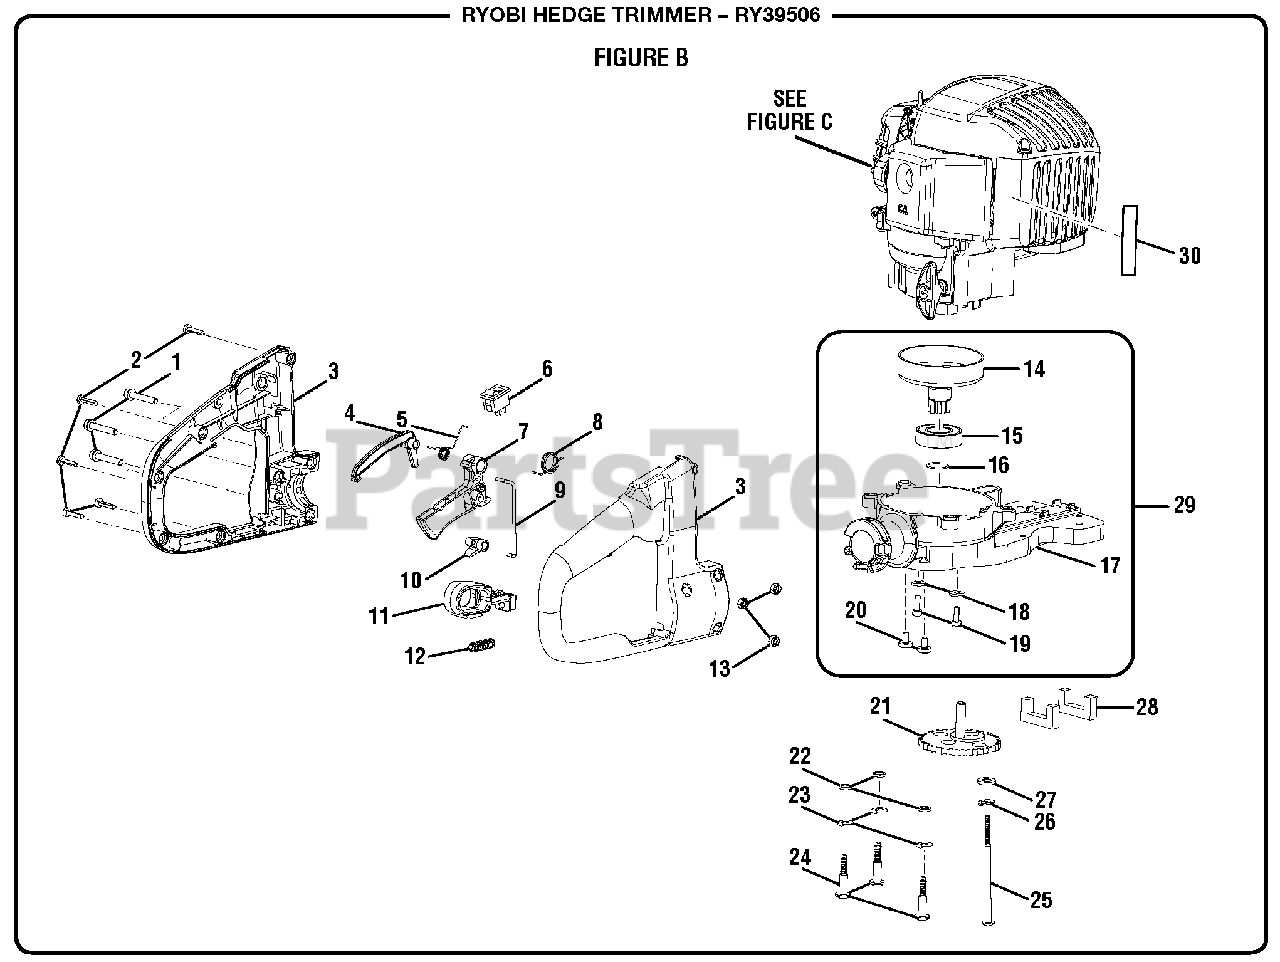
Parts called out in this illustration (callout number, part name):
1	Screw (M5 x 28 mm)
2	Screw (M4 x 18 mm)
3	Rear Handle Housing Assembly
4	Interlock Level
5	Trigger Lock Spring
7	Throttle Trigger
8	Trigger Spring
9	Lock Level Wire
10	Rotate Level
11	Rotate Lock Puller
12	Rotate Lock Spring
13	Lock Nut (M5)
14	Clutch Drum Assembly
15	Ball Bearing (6003ZZ)
19	Screw (M4 x 8 mm)
20	Screw (M4 x 8 mm)
21	Big Gear Assembly
23	Spring Washer
24	Screw (M5 x 30 mm)
25	Screw (M4 x 83 mm)
26	Spring Washer
28	Felt Seal
29	Gear Box Assembly
30	Combustion Warning Label
